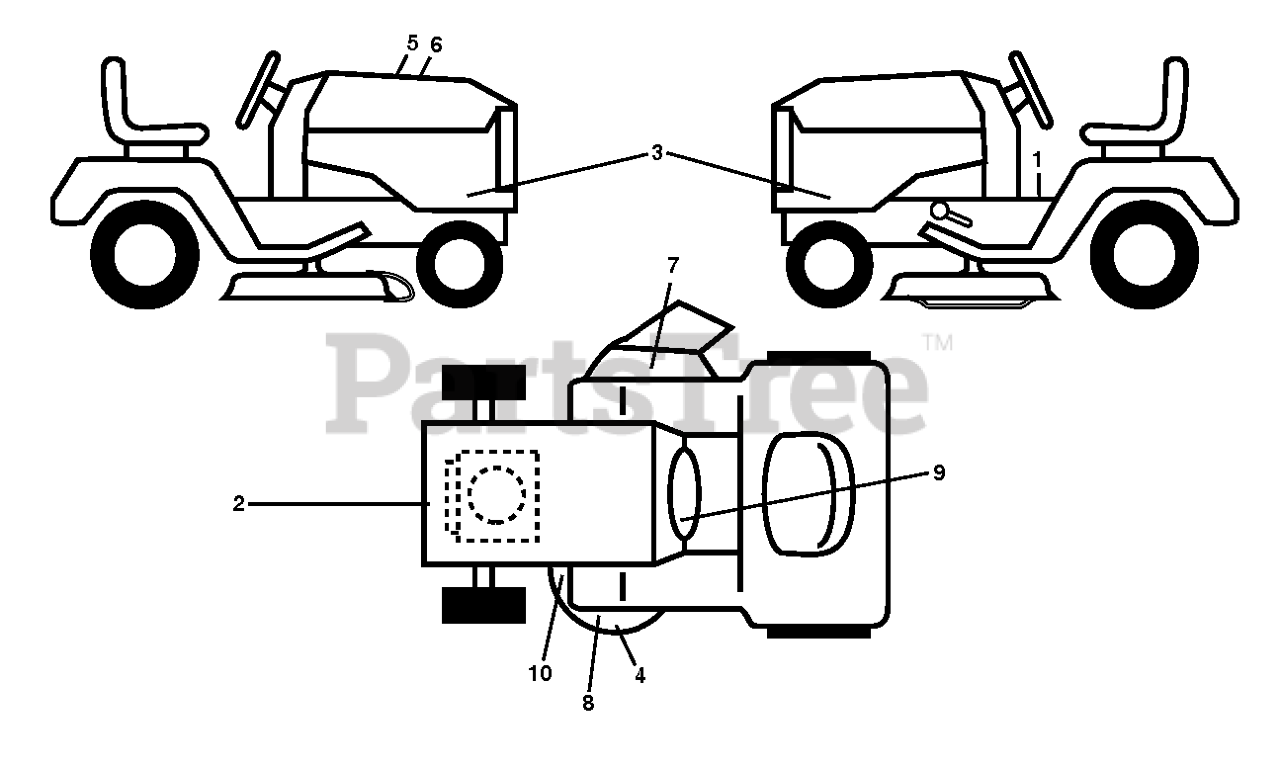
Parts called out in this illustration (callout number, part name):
1	DECAL.FENDER.WARNING.ENGLISH
2	DECAL.ENG.BS.ENDUR.24HP.382021
4	DECAL
4	DECAL.MOWER.CAUTION.TENSION.AR
5	DECAL.WARNING.CUST.RESP.E85.
7	DECAL, DECK DEFLECTOR, WARNING
7	DECAL.DECK.DEFLECTOR.WARNING
8	DECAL.DECK.STAMP.BIOCLIPCMP.HU
9	DECALS.WARN.CA.SPKARREST/PROP
10	DECAL.DECK.BELT.ROUTING.48/54
10	DECAL.MOWER.SCH.48/54.PREM
